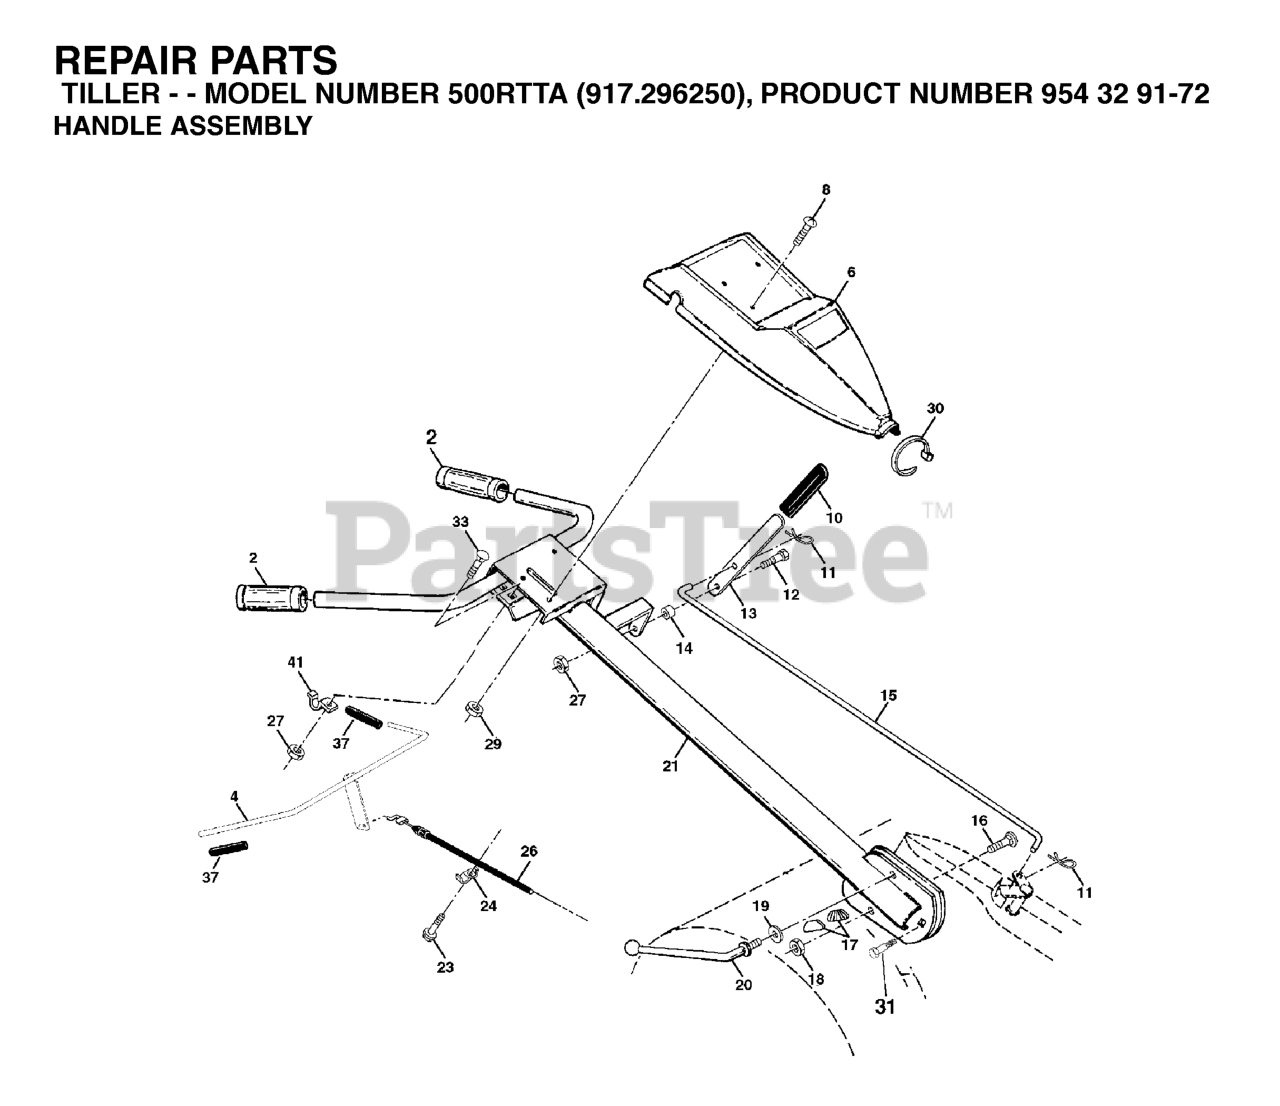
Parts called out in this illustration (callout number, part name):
2	KIT.GRIP.HANDLE.5.00.BLK.VINYL
4	CONTROL BAR ASSY
6	RP PANEL, CONTROL
8	SCREW.PNHD.10-24
10	GRIP T
11	RETAINER M
12	SHOULDER BOLT ST
13	SHIFT HANDLE CRT
14	GROMMET.RUBBER.CRT.TILLER
15	SHIFT ROD CRT
16	BOLT D
17	LOCK.HANDLE.CRT
19	WASHER CRT
20	LEVER.LOCK.CRT
21	REPL BY 532 1805-17
23	TAPPING SCREW
24	CONDUIT.CLIP.PLATED
26	CABLE.CLUTCH
27	NUT T
29	NUT **
30	TIE CABLE CRT
31	BOLT.PIVOT
37	GRIP BAR CRT(1)
41	CLAMP.BAR.CRT.BLACK
